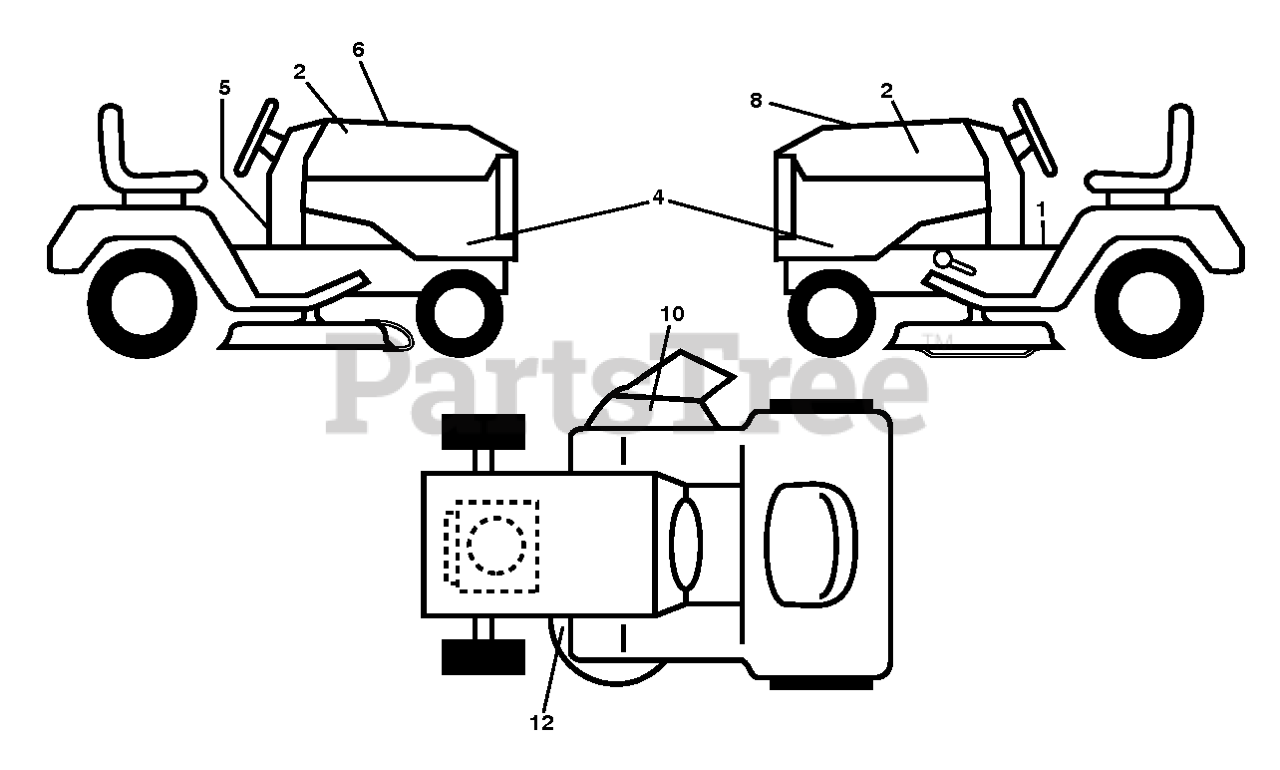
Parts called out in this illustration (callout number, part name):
1	DECAL.FENDER.WARNING.ENGLISH
2	DECAL.BADGE.170MM.TEXTLOGO.
5	DECALS.WARN.CA.SPKARREST/PROP
6	DECAL.RPL.KW.FR.TLW.42E.
8	DECAL.WARNING.CUST.RESP.E85.
10	DECAL, DECK DEFLECTOR, WARNING
12	DECAL.V-BELT.SCH.42/46"MEC/ELE
